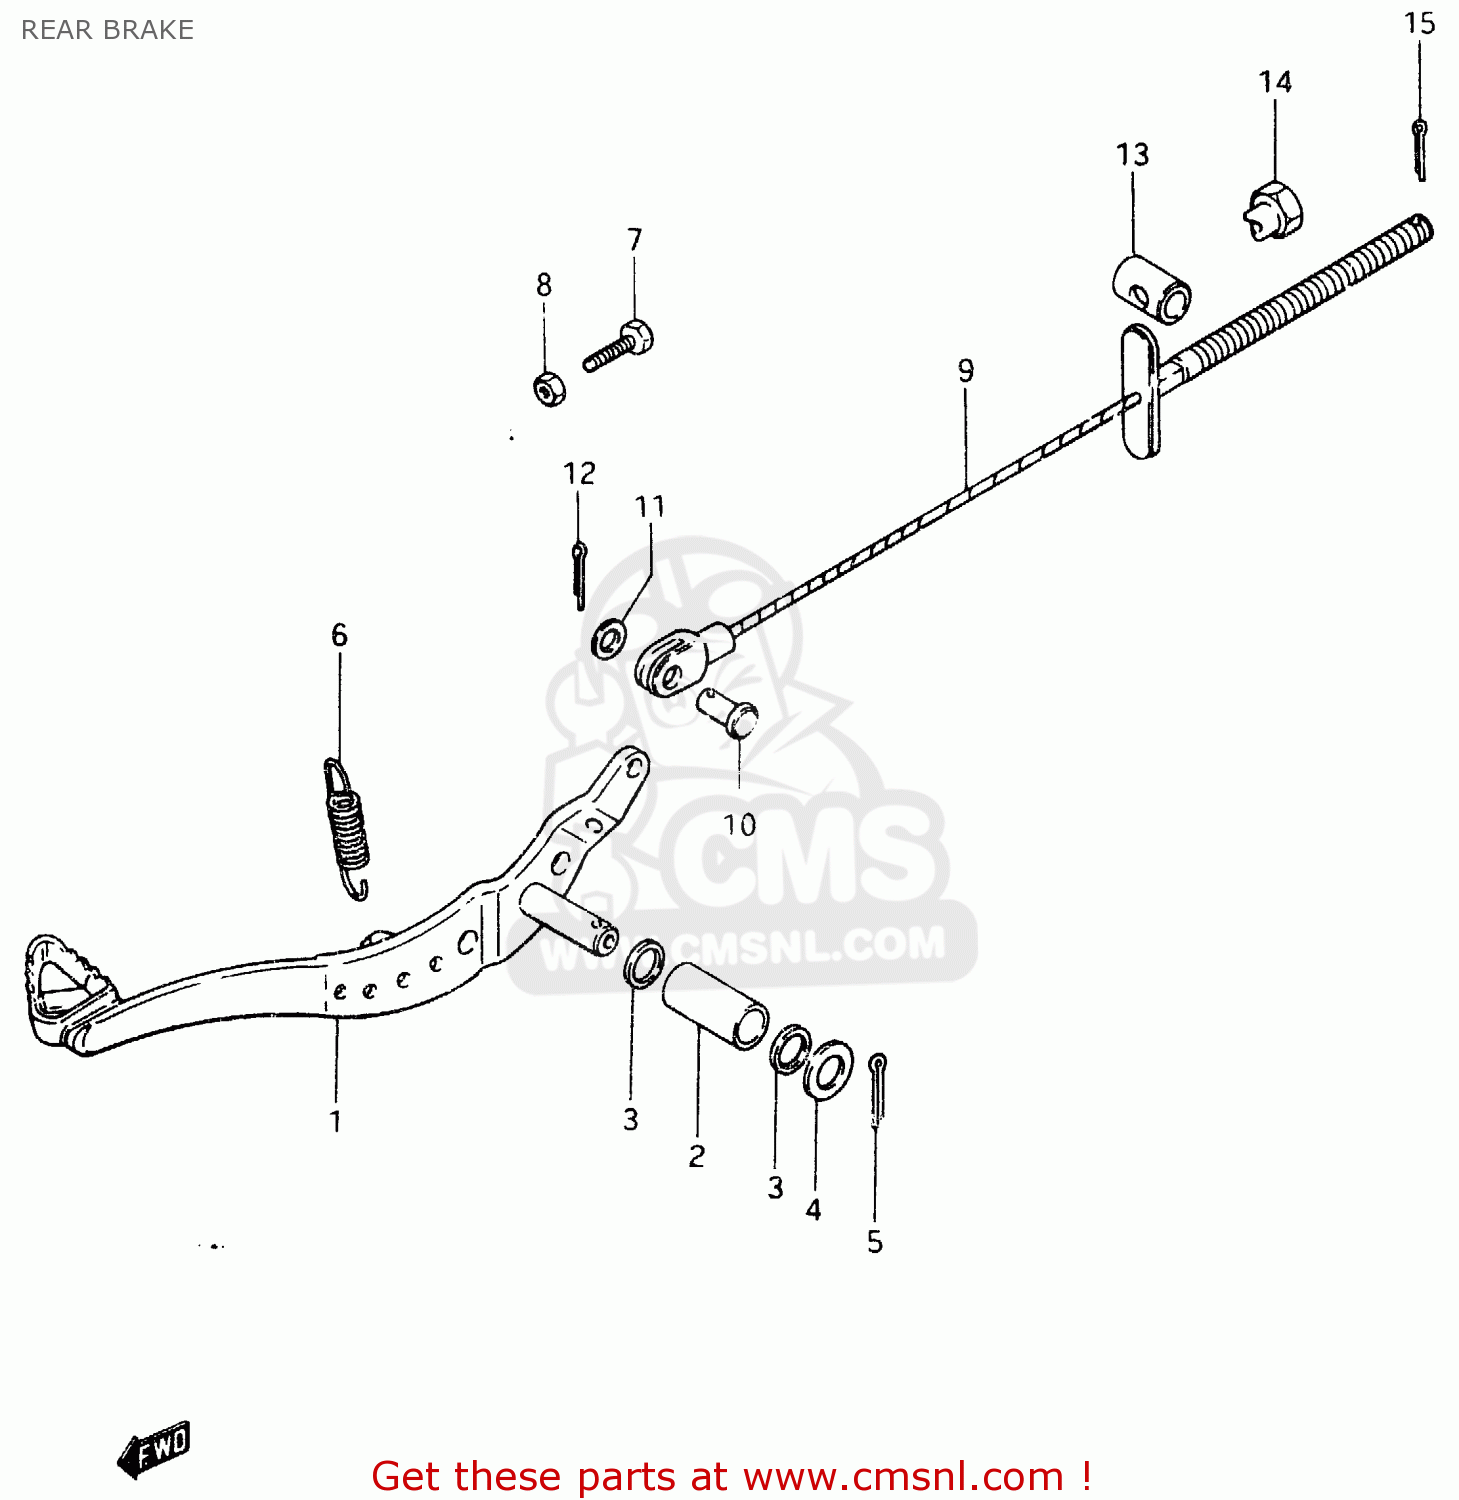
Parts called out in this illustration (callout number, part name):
1	PEDAL,BRAKE
2	BUSHING
3	O RING(D:2.2,ID:11.8)
4	WASHER
5	PIN 30X20
6	SPRING
7	BOLT(6X23)
8	NUT
9	CABLE,REAR BRAKE
10	PIN(L:17.5)
11	WASHER
12	PIN 20X20
13	PIN
14	NUT
15	PIN
